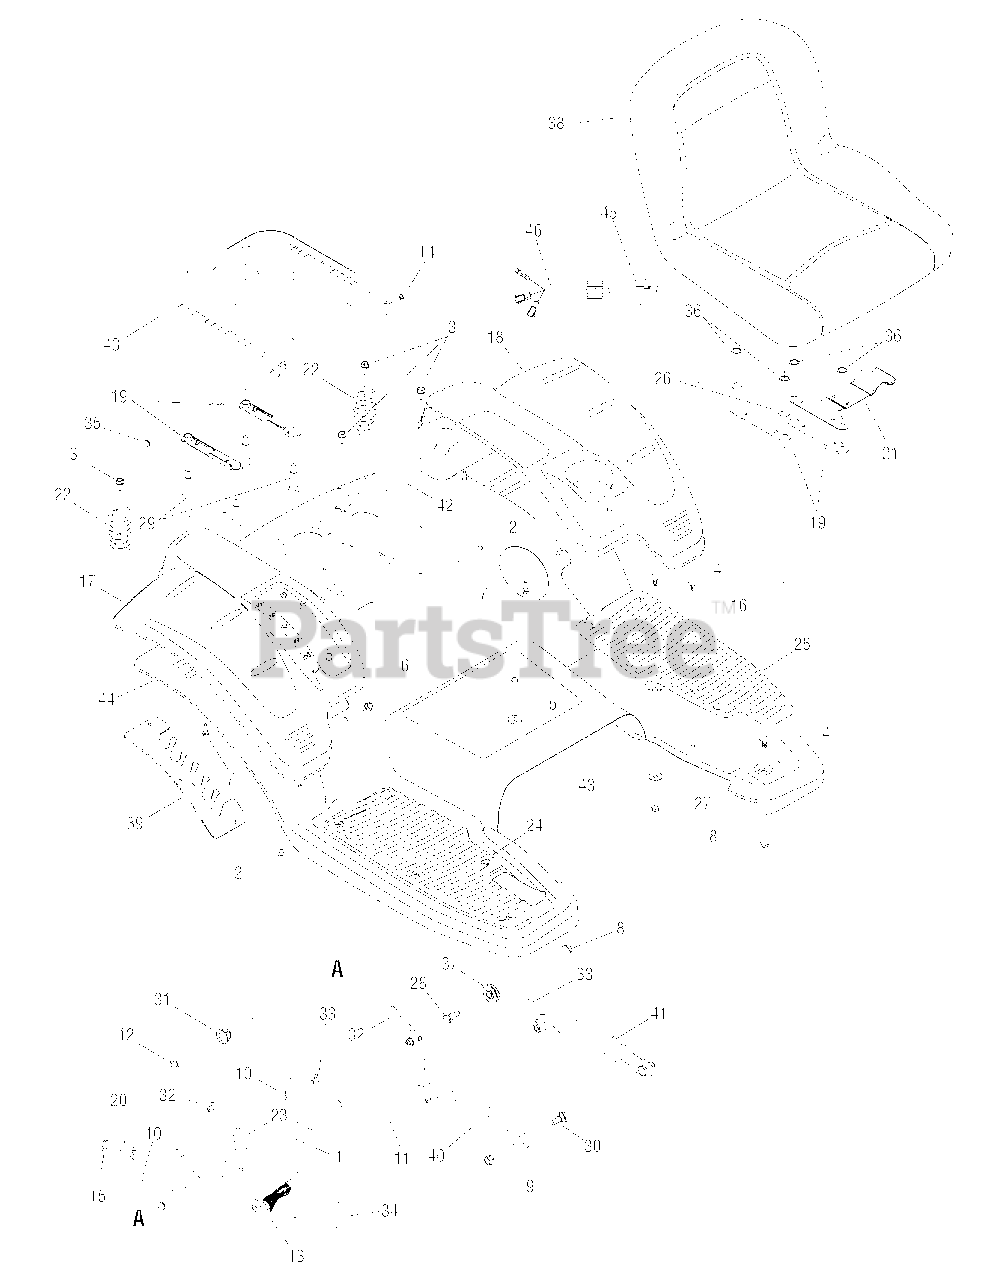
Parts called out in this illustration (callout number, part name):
2	Screw, Hex Wash Hd. H/L, 1/4-15 x .5
3	Screw, Hex Wash Hd. Tapp, 5/16-18 x .75
4	Screw, Carriage, 5/16-18 x 75
5	Screw, Hex Wash Hd. Tapp, 1/4-20 x .5
6	Screw, Hex Wash Hd. Tapp, 5/16-12 x .75
7	Screw, Hex Wash Hd. Tapp, 1/4-15 x .75
8	Nut, Hex Flange Insert Lock, 5/16-18 GrF
9	Nut, Hex Flange Insert Lock, 3/8-16 GrF
10	Pin, Internal Cotter
11	Pin, Cotter, 3/32 x 1.0
12	E-ring, .625 Shaft
13	Grip, Handle
14	Nut, Speed, .3125 Dia.
15	Nut, Speed, .5
16	Clip, Ratchet
17	Cover, Rear Fender RH
18	Cover, Rear Fender LH
19	Spacer, Seat Adjust
20	Spring, Lift Handle Torsion
21	Spring, Seat Adjust
22	Spring, Compression, 1.71 x 3.25 x .23
23	Spring, Extension, .865 x 4.68
24	Pad, Foot RH
25	Pad, Foot LH
26	Washer, Flat, .535 x .93 x .09
27	Washer, Flat, .344 x 1.0 x .063 HT
28	Bolt, Shoulder, .496 x 2.5:3/8-16
29	Bolt, Shoulder, .496 x 1.525:3/8-16
30	Bolt, Shoulder, .625 x .175:3/8-16
31	Bearing, Hex Flange,
32	Cable, Lift, 16.16 Lg
33	Cable, Lift, 16.16 Lg
34	Handle, Lift
35	Rod, Seat, 5/16 x 11.62
36	Spacer, .51 x .75 x 1.0
37	Pulley, Roller
38	Seat, High Back
46	Harness, Seat Switch Jumper
